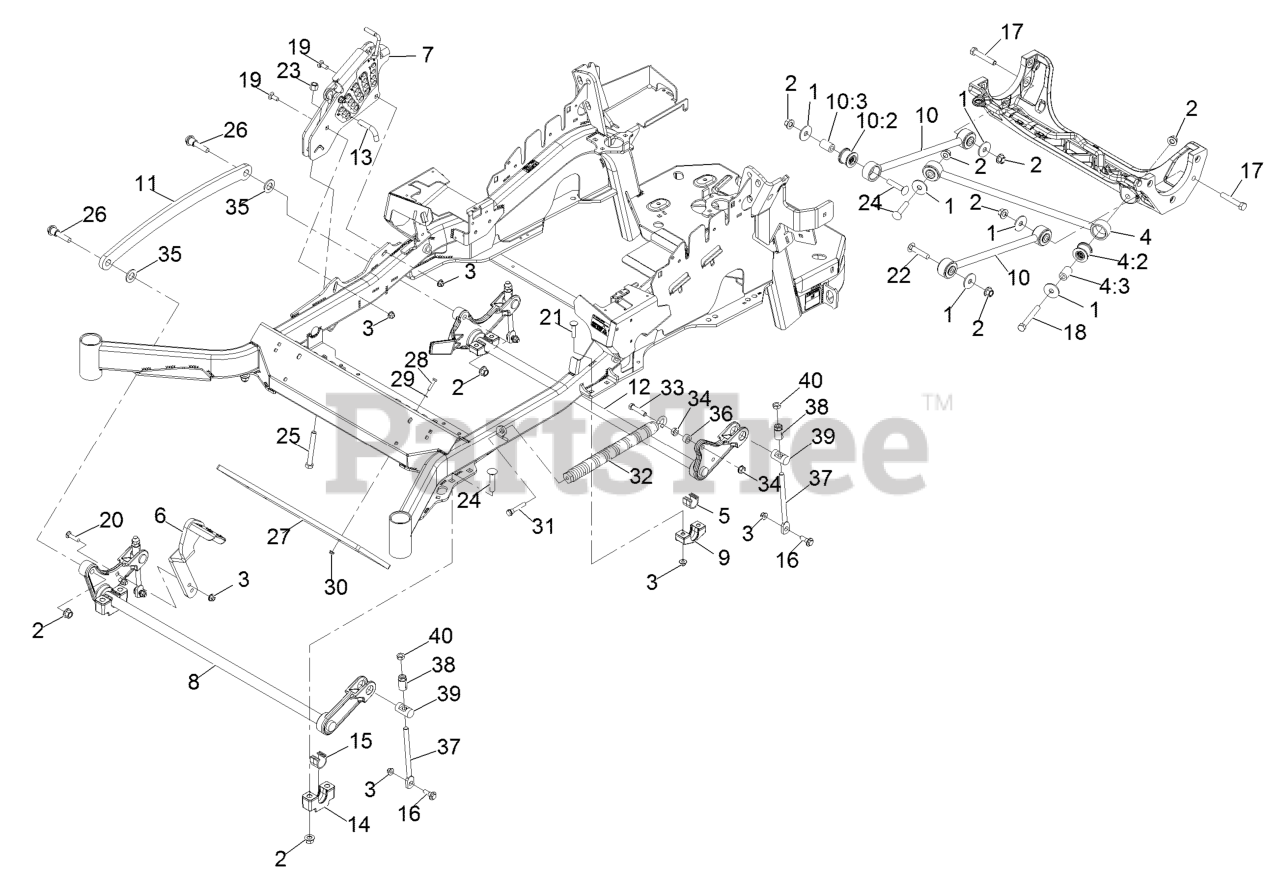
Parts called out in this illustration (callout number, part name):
1	WASHER-THRUST
2	Nut-Lock 1/2-13
3	NUT-HF, NI
4	PANHARD ROD ASM
4:2	BUSHING-SUSPENSION, RUBBER
5	BEARING-CROSS SHAFT, REAR
6	LEVER-FOOT
7	HOC ASM
8	DECKLIFT-FRONT
10	DECK STRUT ASM
10:2	BUSHING-SUSPENSION, RUBBER
11	LINK-LIFT, DECK
12	LIFT-DECK, REAR
13	PIN-HOC
14	SUPPORT-CROSS SHAFT, BEARING
15	BEARING-CROSS SHAFT, FRON
16	SCREW-SHOULDER, HHF
17	SCREW-HH
18	SCREW-HH
19	BOLT-CARR
20	SCREW-CARR
21	SCREW-CARR
22	SCREW-CARR
23	NUT-LOCK, NI
24	Bolt-Carriage 1/2-13 X 2 1/2 Spl Neck
25	BOLT-TAP
26	SCREW-HHF, SHOULDER
27	WEIGHT,TOE BOARD
28	SCREW-HH
29	WASHER-FLAT
31	BOLT-SHOULDER
32	SPRING-EXTENSION
33	SCREW-HH
35	WASHER-FLAT
37	LINK-ADJUSTER, DECK LIFT
38	ADJUSTER-LIFT, DECK
39	TRUNNION
40	NUT-JAM
